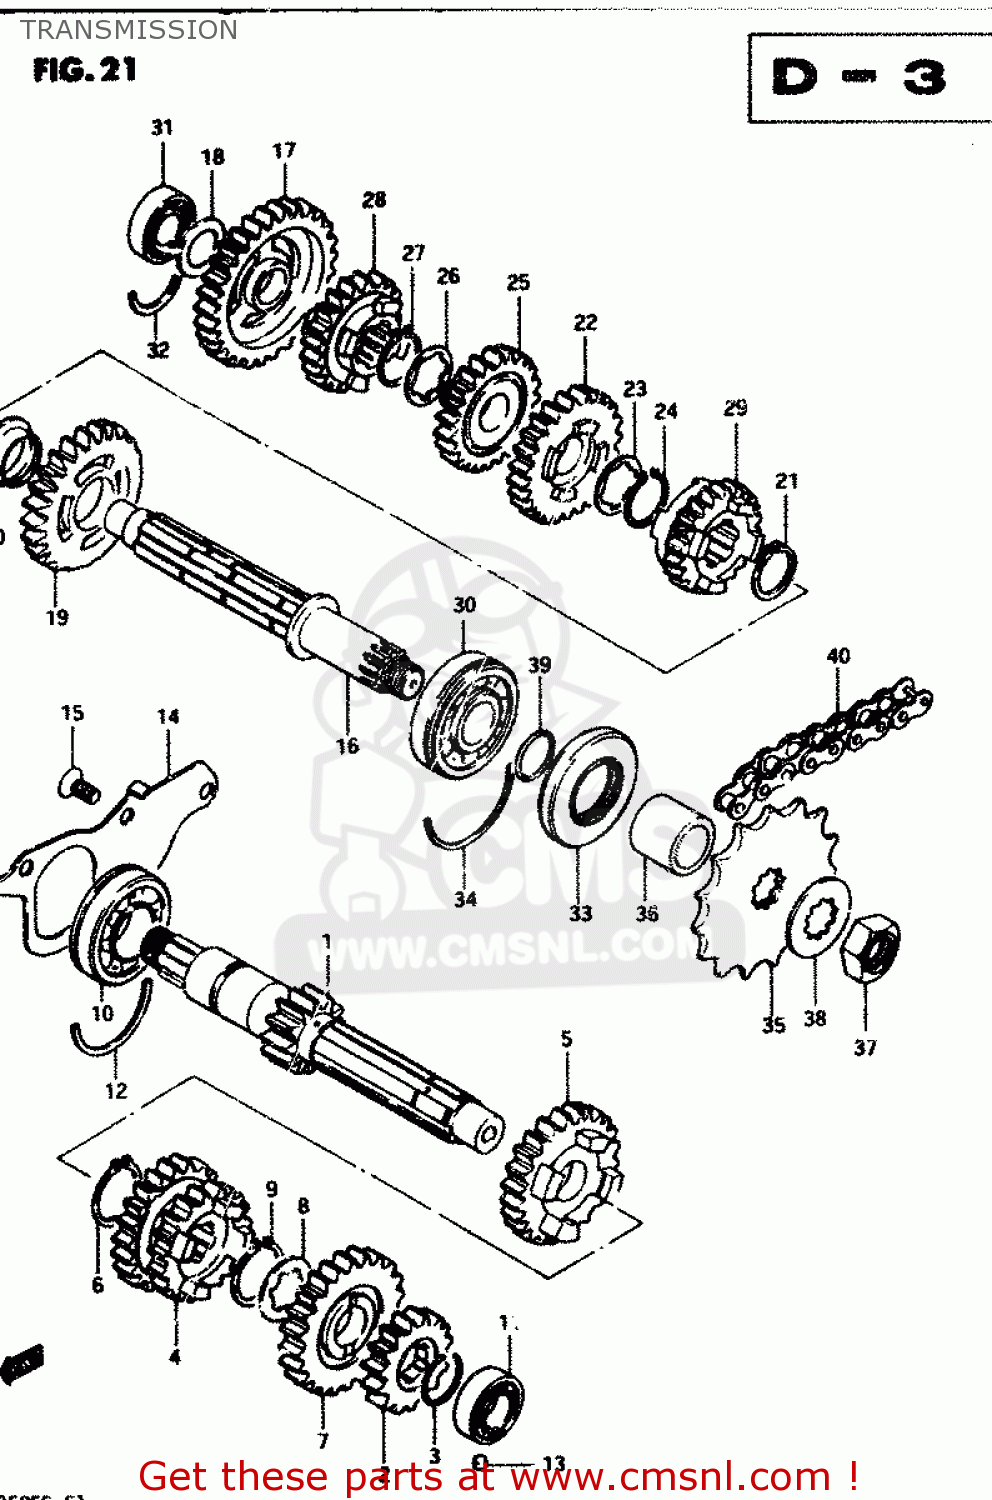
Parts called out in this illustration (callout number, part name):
1	SHAFT,COUNTER
2	GEAR,SECOND DRIVE
3	CIRCLIP
4	GEAR,THIRD/FOURTH DRIVE
5	GEAR,FIFTH DRIVE
6	CIRCLIP
7	GEAR,SIXTH DRIVE
8	WASHER,LOCK
9	CIRCLIP
10	BEARING
11	ROLLER BEARING (17X31X1
12	C RING
13	PIN
14	RETAINER,BEARING
15	SCREW
16	SHAFT,DRIVE
17	GEAR,FIRST DRIVEN
18	WASHER,THRUST
19	GEAR,SECOND DRIVEN
20	BUSH
21	CIRCLIP
22	GEAR,THIRD DRIVEN
23	WASHER,LOCK
24	CIRCLIP
25	GEAR,FOURTH DRIVEN
26	WASHER,LOCK
27	CIRCLIP
28	GEAR,FIFTH DRIVEN
29	GEAR,SIXTH DRIVEN
30	BEARING
31	BEARING, RH
32	C RING
33	SEAL,OIL(28X52X11.5)
34	C RING
35	SPROCKET,ENGINE(NT:14)
36	SPACER (20X28X25.2)
37	NUT
38	WASHER,LOCK
39	O RING(D:1,ID:19.5)
40	CHAIN, DRIVE (520X11OLE)
